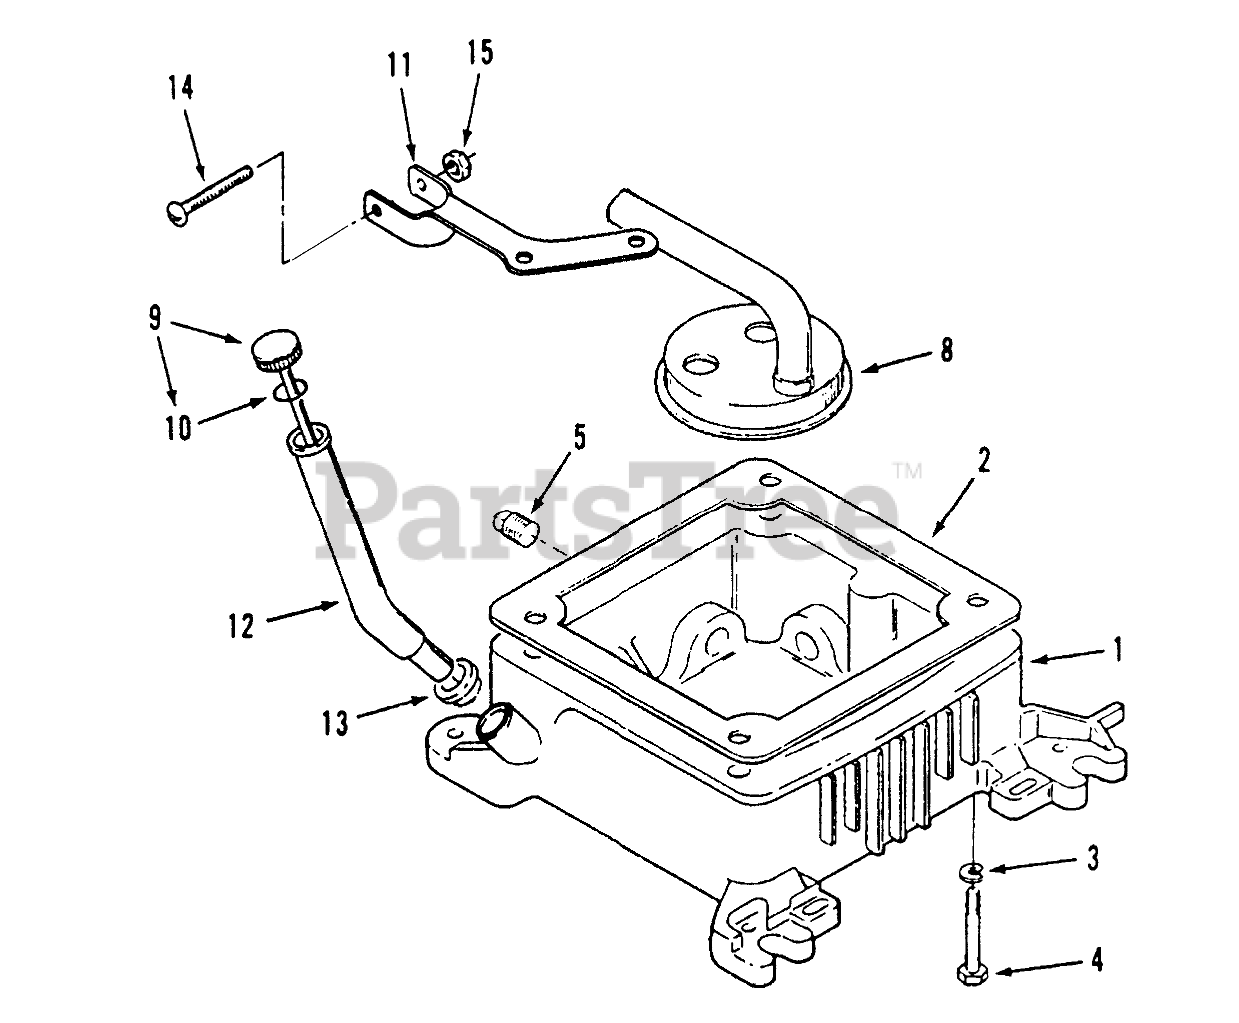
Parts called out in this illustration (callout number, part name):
1	Base-Oil (Incl. All Plugs & Plug Gasket)
2	GASKET
3	WASHER-FLAT
4	HHCS 3/8-16 X 3 3/4
5	PLUG - SQUARE HEAD
8	OIL CUP ASM
9	Cap-Oil Fill & Indicator (Incl. "O"Ring)
10	SEAL 0-RING
11	BRACKET-FILL TUBE
12	TUBE-OIL FILL
13	SEAL-OIL FILL TUBE
14	SCREW - PAN HEAD
15	NUT - SPEED
